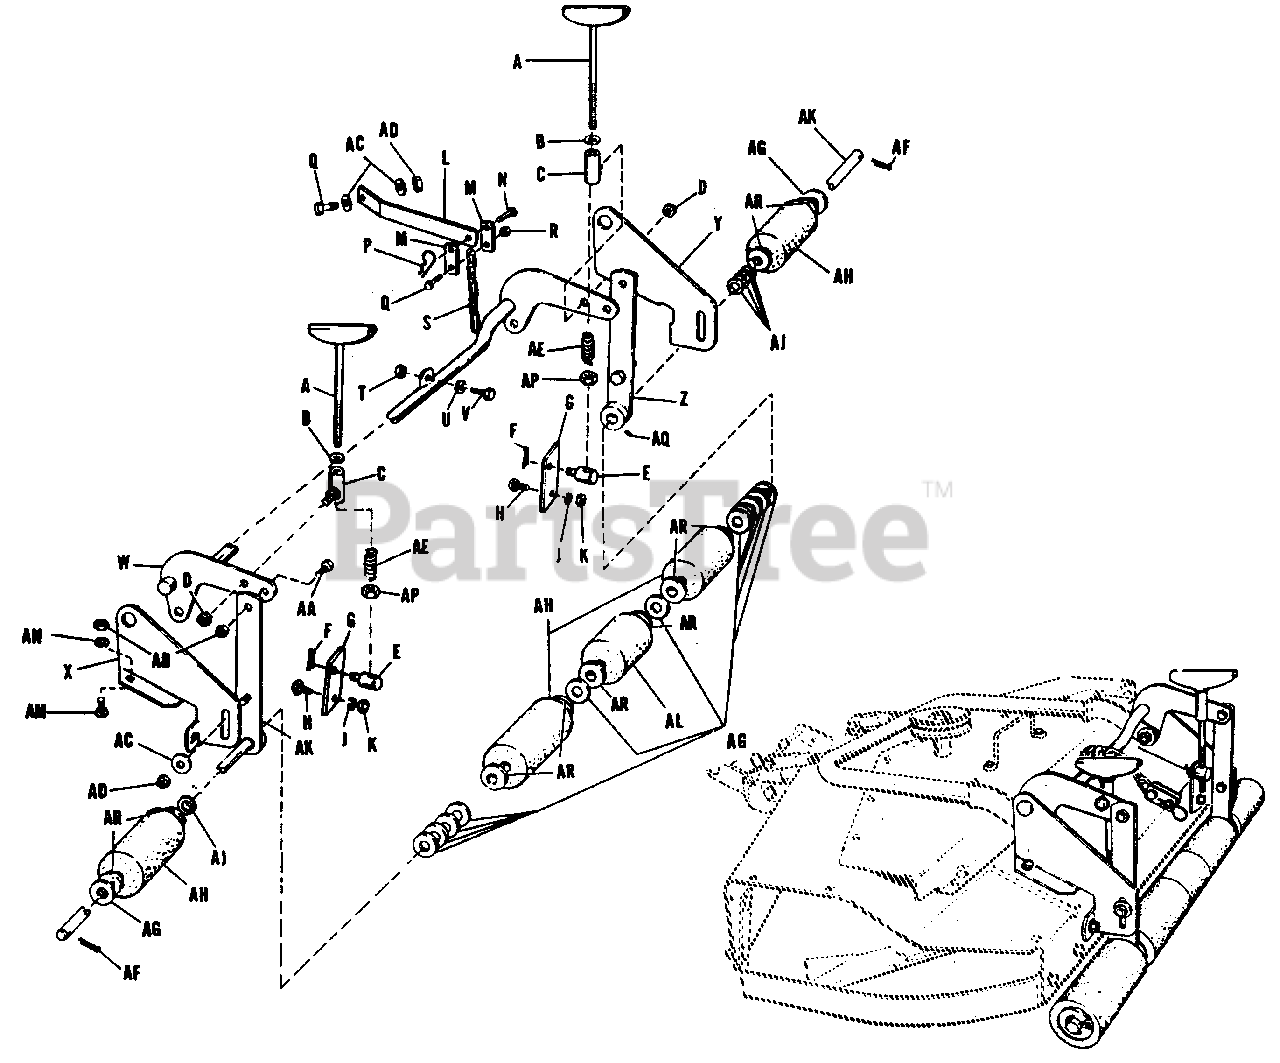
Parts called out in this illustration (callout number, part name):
A	Screw Assembly, Adjusting
B	Washer, Plain, 3/8"
C	Socket Assembly, Crank
D	Nut, Hex, Full, Lock, 3/8"-16 NC
F	Cotter Pin, 3/32" x 3/4" lg.
G	Link, Lift
H	Bolt, Carriage 3/8"- 16 NC x 3/4" lg.
J	Washer, Lock 3/8"
K	Nut, Hex, Full, 3/8"-16 NC
L	Lever, Mower Lift
M	Link, Mower Lift
P	Clip, Spring
Q	Capscrew, Hex Hd., 3/8"-16 NC x 1" lg.
R	Nut, Hex, Full, Lock, 3/8"-16 NC
T	Nut, Hex, Full, Lock, 3/8"-16 NC
U	3/8" Washer
V	Capscrew, Hex Hd., 3/8-16 x 1" lg
W	Arm Assembly, Rocker
X	Bracket, Roller, R.H.
Y	Bracket, Roller, L.H.
Z	Bar Assembly, Roller
AA	Capscrew, Hex-Hd., 3/8"-16 NC x 1" lg.
AB	Nut, Hex, Full, 3/8"-16 NC
AC	Washer, Plain, 3/8"
AD	Nut, Hex, Full, Lock, 3/8"-16 NC
AE	Spring, Adj. Screw
AF	Pin, Cotter, 3/16" x 1" lg.
AH	Roller W/Bushing
AK	Shaft & Support Arm.
AL	Roller W/Bushing
AM	Bolt, Carriage, 3/8"-16 NC x 3/4" lg.
AN	Washer, Lock, 3/8"
AP	Nut, Hex, Full 3/8"-16 NC
AQ	Set Screw 1/4"-20 NC x 5/16" lg.
